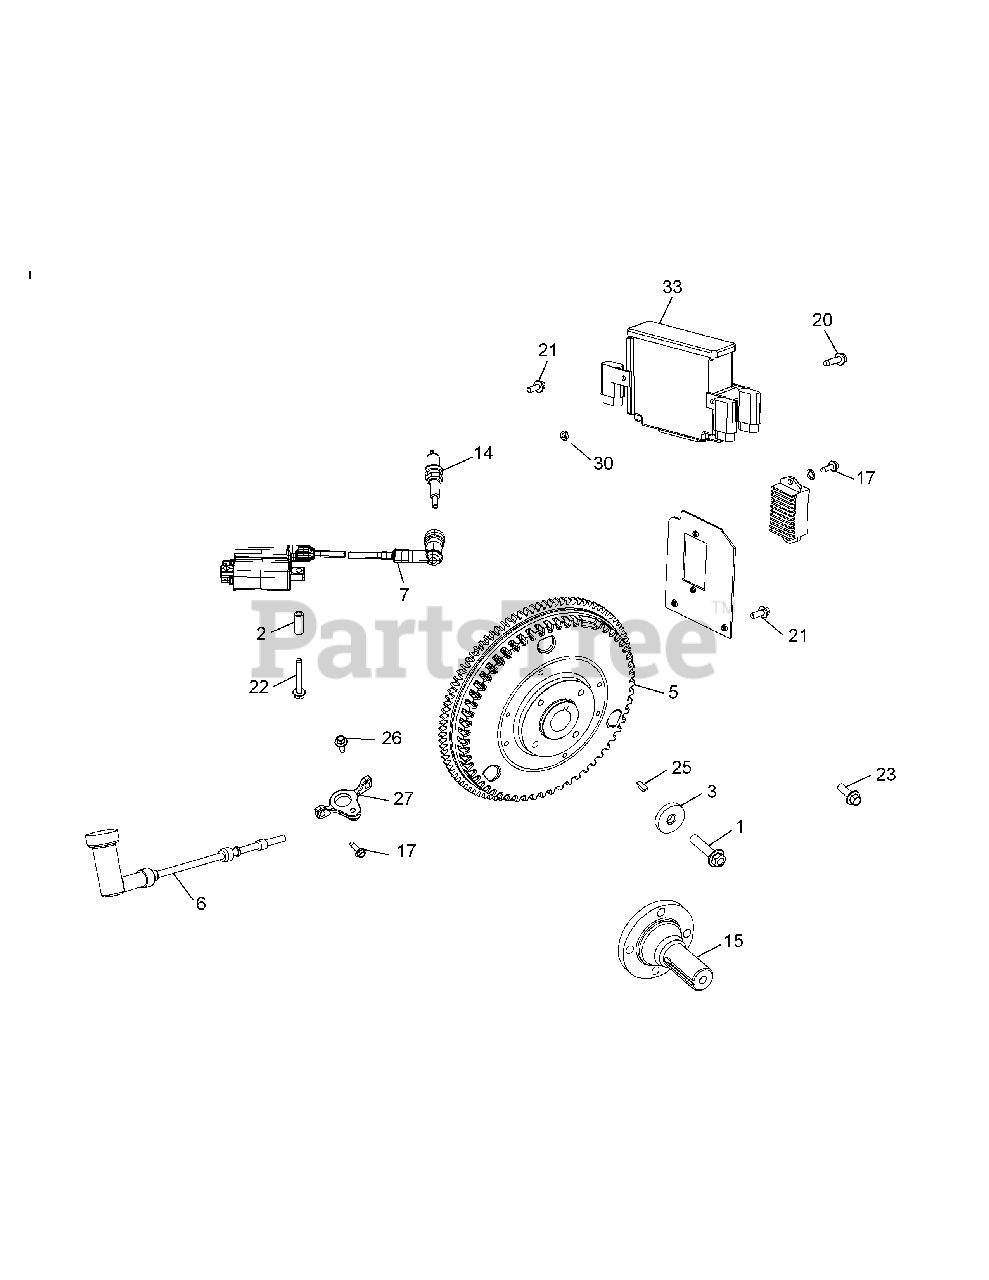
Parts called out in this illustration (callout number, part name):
1	Screw, Flg M10x1.5x45 - (#25086361S)
3	Washer, Flat 13/32"
5	Flywheel, Painted
6	Boot, Spark Plug
7	Coil, Ignition (Includes 11)
14	Spark Plug (Includes 11)
15	Shaft, Front Drive
20	Screw,Flg Thd Frm M6x1.0x20
21	Screw, Flng M6 x 1.0 x 16
22	Screw, Thrd Frm M6x1.0x45
23	Screw, Flg M8x1.25x25
25	Key, 3/16" X 5/8"
26	Screw, Thread Forming
27	Bracket, Speed Sensor
30	Nut, Mach Screw #10-32 Grd 2
33	Module, Engine Management
